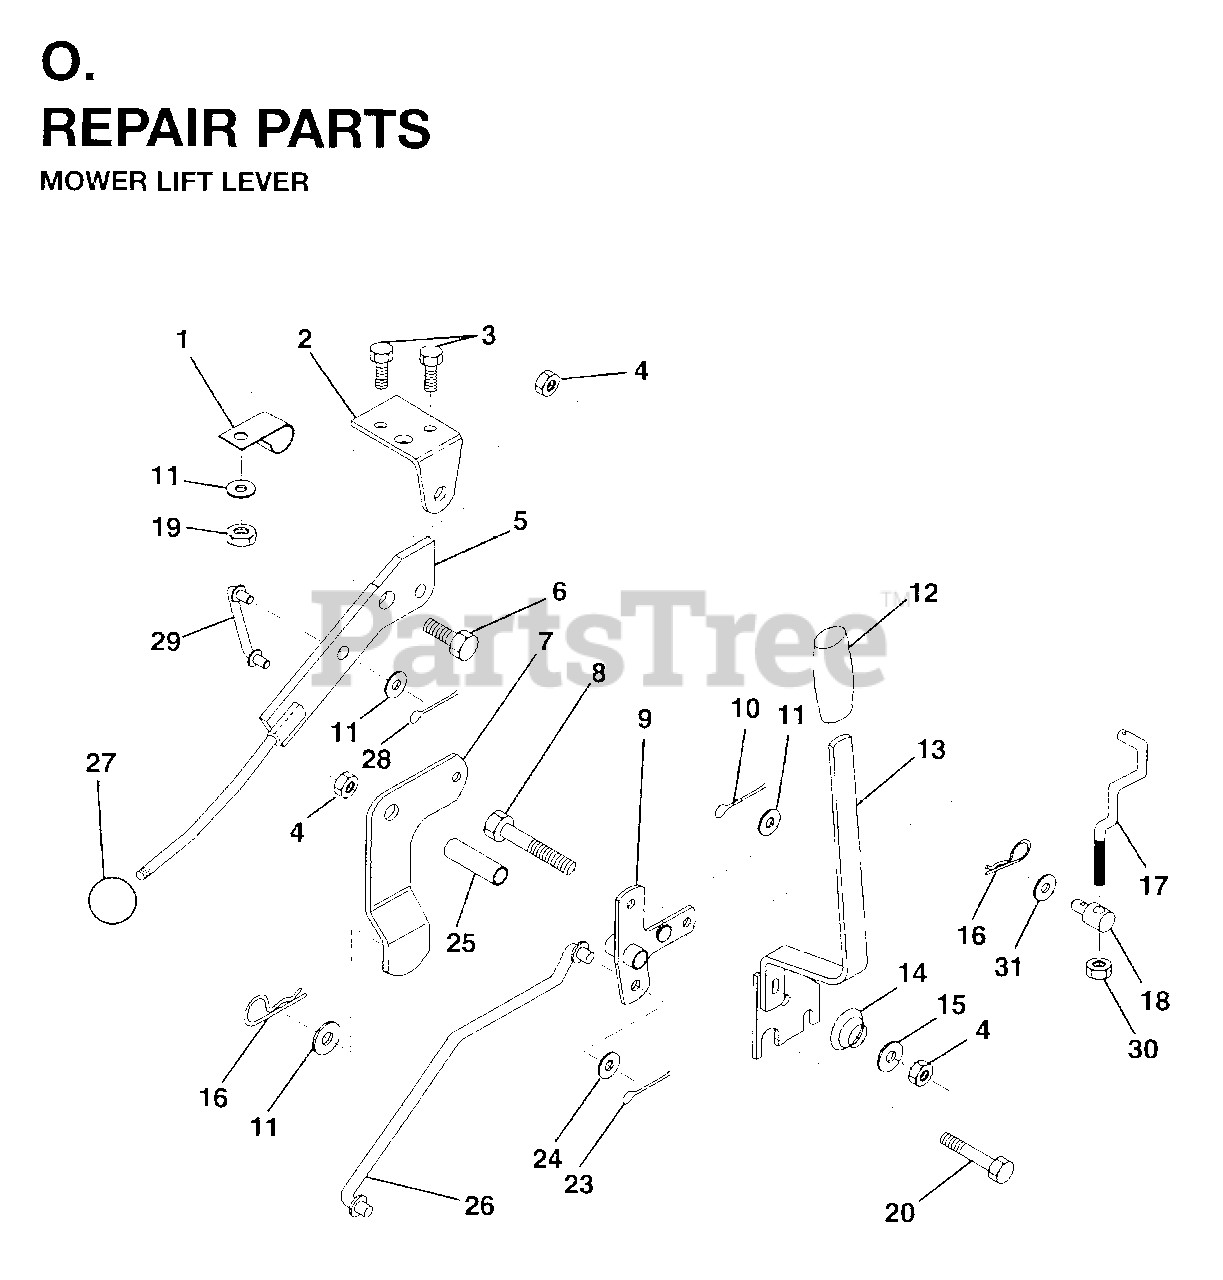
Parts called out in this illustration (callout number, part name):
1	CLIP,INSULATOR
2	BRKT CLUTCH
3	BOLT
4	LOCKNUT
5	CLUTCH LEVER
6	BOLT, SHOULDER LT
7	ASSEMBLY MOWER CLUTCH ARM
9	BELLCRANK,LIFT
10	COTTER PIN
11	WASHER
12	GRIP HANDLE
13	LIFT HANDLE ASSY
14	SPRING COMPRESSIO
15	WASHER
16	SPRING.RETAINER
17	LINK LIFT FRT
19	NUT.CROWNLOCK.1/4
23	PIN COTTER
24	WASHER - M12
25	TUBE SPACER
27	KNOB
28	COTTER PIN
29	LINK MOWER CLUTCH
30	NUT.HEX.3/8-16UNC
